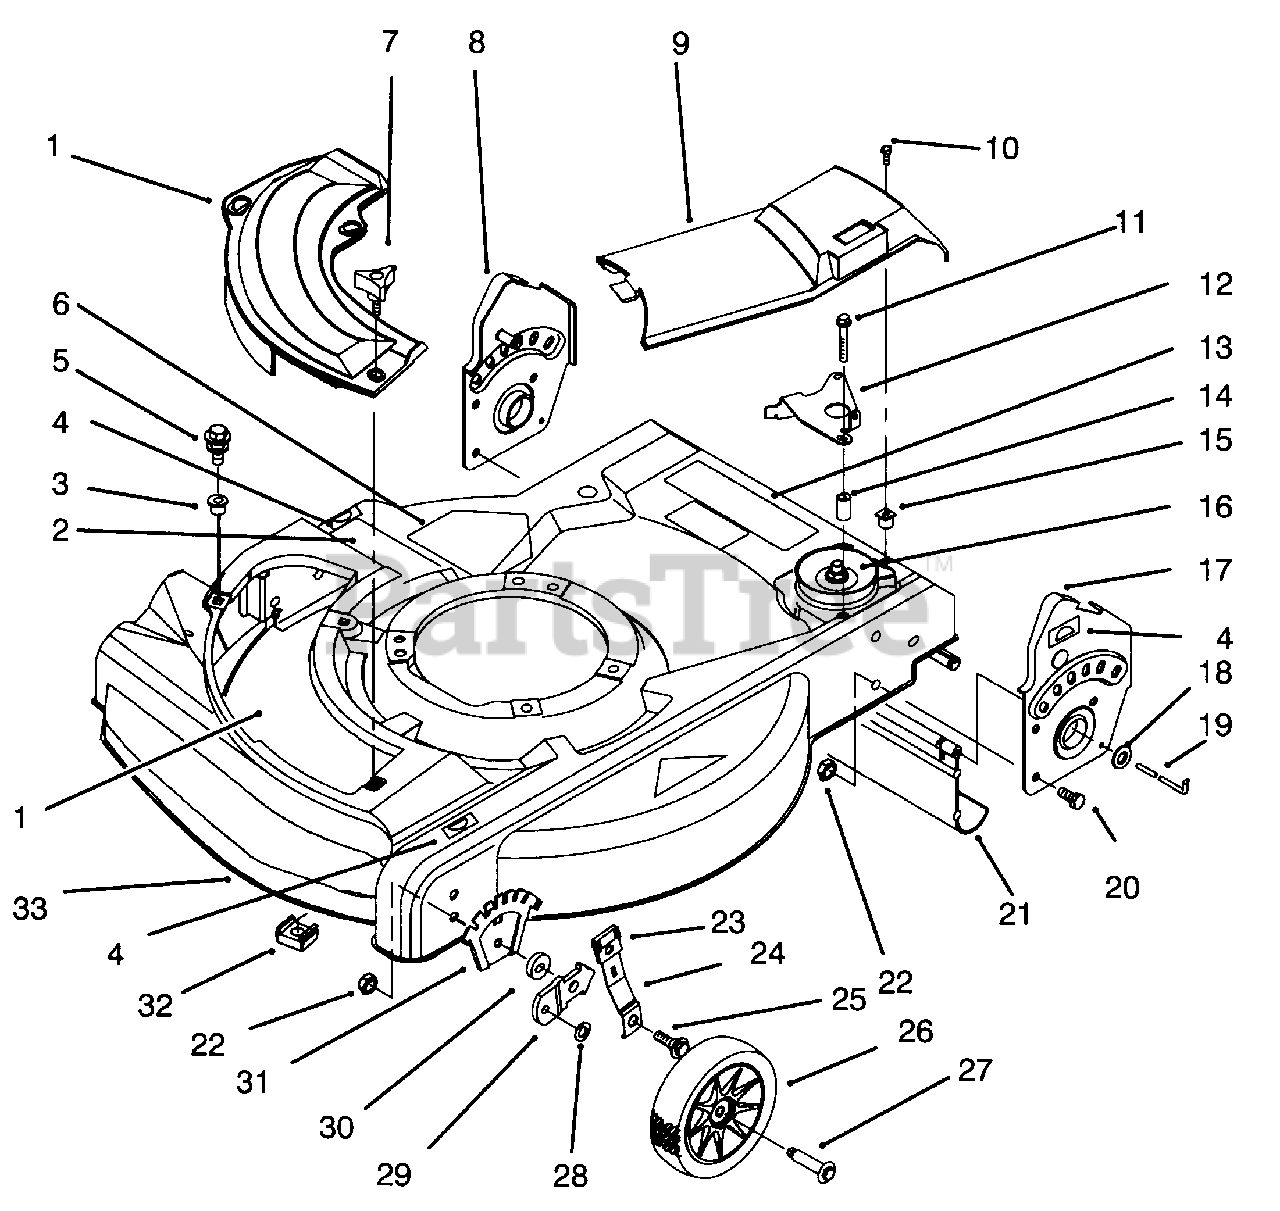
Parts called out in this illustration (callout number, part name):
1	Plate-Cover, Mulch
2	Decal-Danger
3	Grommet-Plastic
4	Decal-H.O.C. L.H.
5	Screw-Thread Forming
6	Decal-Danger
7	Knob
8	Handle Bracket Ass'y-RH
9	Cover-Drive
10	Screw
11	Screw-Thread Forming
12	Guide-Transmission
13	Decal-Warning
14	Bushing-Actuator Plate
15	Grommet-Shroud Mtg.
16	Gear Case Ass'y
17	Handle Bracket Ass'y-L.H.
19	Rod-Trailing Shield
20	Screw-Hex. Hd.
21	Shield-Trailing
23	Knob-H.O.C.
24	Arm-Spring
25	Bolt-Shoulder
26	Wheel Assembly-6"
27	Bolt-Wheel
29	Bracket-H.O.C.
31	Plate H.O.C.
32	Nut-Cage
33	Housing & Baffle Ass'y (Incl. Ref. #1, 2, 3, & 13)
